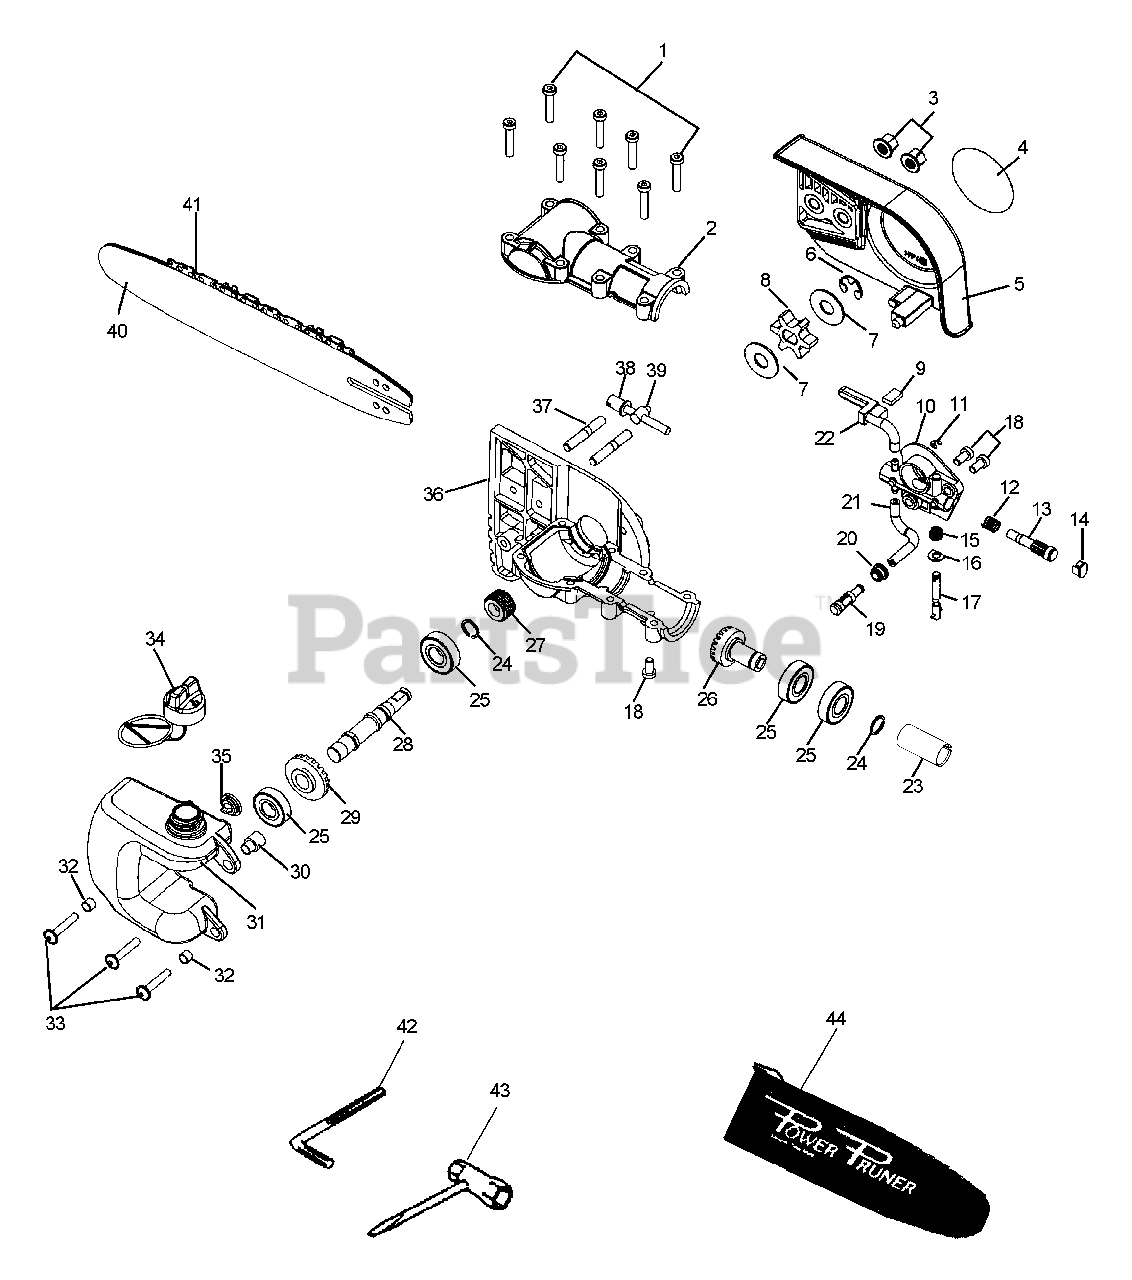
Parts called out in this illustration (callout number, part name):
1	SCREW M5×.25
2	COVER, GEAR CASE
3	NUT, FLANGE M6
4	LABEL, ECHO
5	GUARD, SPROCKET
6	RING, RETAINING Ø0.300
7	WASHER 10.2×24.5×1.2
8	SPROCKET, DRIVE
9	PAD, FOAM
10	AUTO-OILER ASSY
13	PLUNGER ASSY
14	CAP, OIL PUMP
17	ADJUSTER, OILER
18	SCREW M5×.8×10
19	FILTER, OIL
20	GROMMET
21	PIPE, IMPULSE 3×6×75
22	PIPE, OIL OUTLET
23	COLLAR - 22
24	RING, SNAP Ø12
25	BEARING, BALL 6201
26	GEAR, BEVEL
27	GEAR, WORM
28	SHAFT, GEAR
29	GEAR, BEVEL
30	COLLAR 6
31	TANK, OIL
32	SPACER 6.2×7.8×6
33	SCREW 5×28
34	CAP ASSY, OIL
35	VENT ASSY
36	CASE, GEAR - LOWER
37	BOLT, STUD 6
39	TENSIONER, CHAIN
40	GUIDE BAR - 10"
41	SAWING CHAIN - 90SG - 10" -- MICRO-LITE
42	TOOL, DRIVER
43	TOOL, BOX SPANNER
44	COVER, GUIDE BAR
